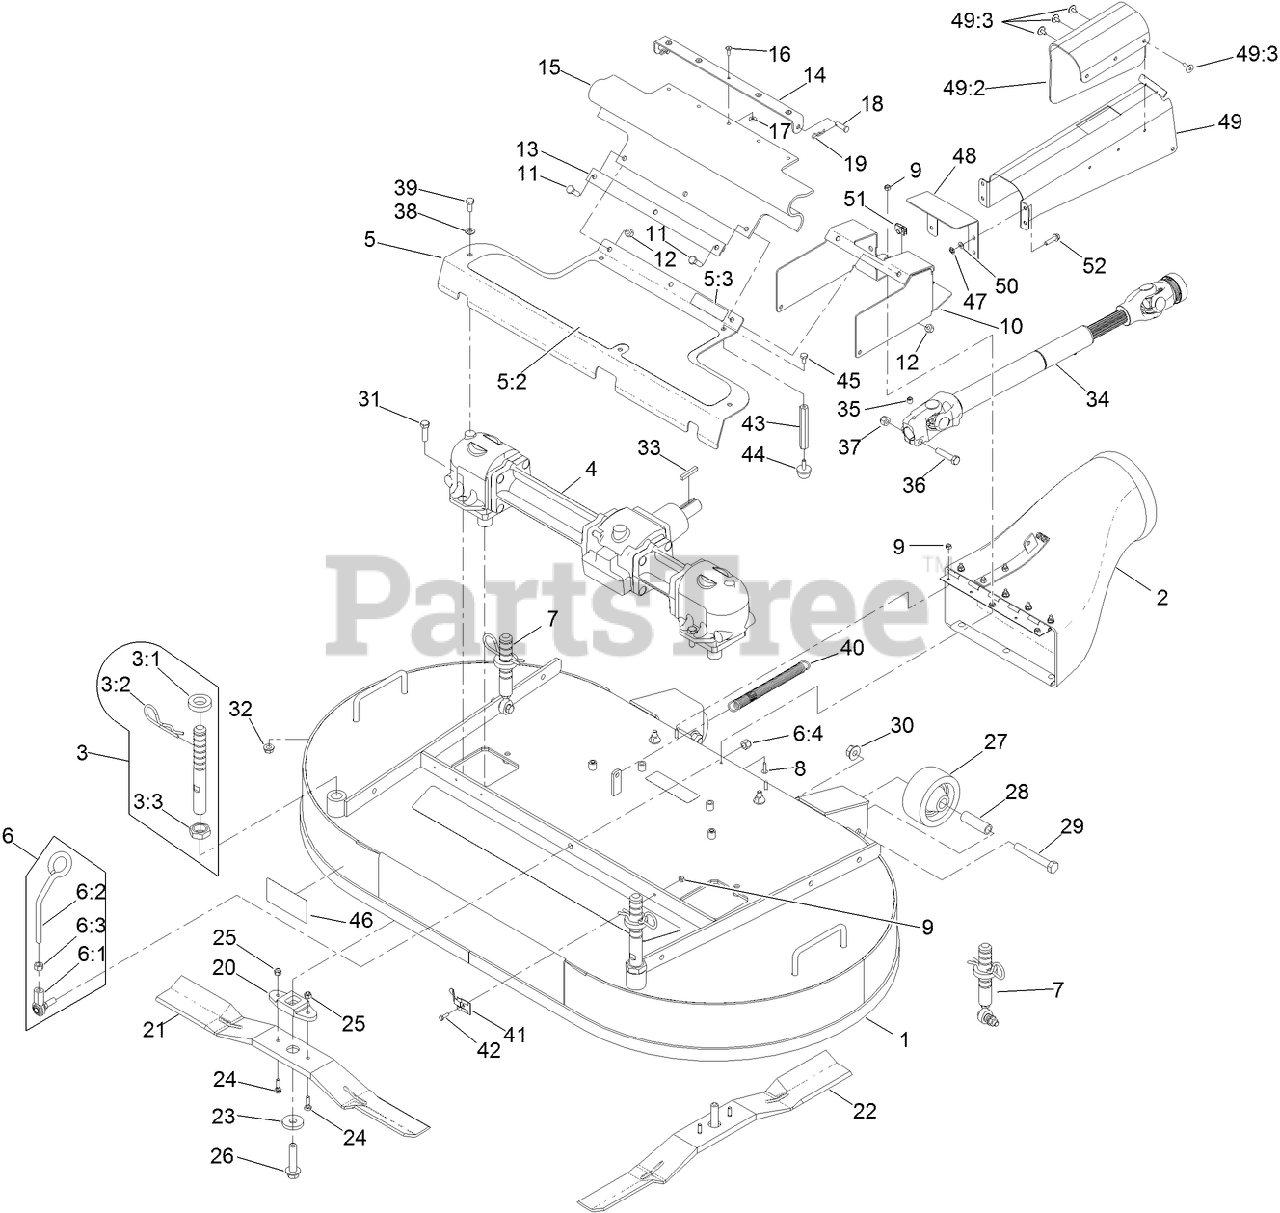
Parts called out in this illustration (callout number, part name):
1	DECK DECAL and BAFFLE ASM
2	DISCHARGE TUBE ASM
3	FRONT DECK HEIGHT ADJUST ASM
3:1	SPACER-DECK SUPPORT
3:2	PIN-CUT HEIGHT
3:3	NUT-JAM
4	GEAR BOX ASM
5	GEARBOX COVER ASM
5:2	PAD-ANTI SKID
5:3	DECAL-DANGER
6	DECK LATCH ASM
6:1	BALLJOINT-RH
6:2	LATCH-DECK
6:3	NUT-HEX
6:4	NUT-LOCK
7	REAR DECK HEIGHT ADJUST ASM
8	SCREW-HEAD, TRUSS
9	NUT-LOCK, NI
10	GUARD-PTO, FRONT
11	SCREW-HH
12	NUT-LOCK, NI
13	STRAP-DRIVE, LINE COVER
14	BRACKET-GUARD, PTO
15	GUARD-PTO
16	RIVET-BLIND
17	WASHER-FLAT
18	PIN-CLEVIS
19	PIN-COTTER
20	DRIVER-BLADE
21	BLADE-25IN, RH
22	BLADE-25IN, LH
23	WASHER
24	BOLT-SHEAR
25	NUT-LOCK, NI
26	BOLT-BLADE
27	ROLLER-DECK
28	SPACER-ROLLER
29	SCREW-HH
30	NUT-HHF
31	SCREW-HH
32	NUT-HHF, WHIZ
33	KEY-SQUARE
34	DRIVE SHAFT ASM
35	SCREW-SET, HSH
36	SCREW-HH
37	NUT-LOCK, NI
38	WASHER-PLAIN
39	SCREW-HH
40	SPRING-EXTENSION
41	CLIP-DECK, HOLD UP ROD
43	STAND-OFF
44	BUMPER
45	SCREW-HH
47	NUT-RETAINER
48	GUARD-PTO
49	PTO GUARD ASM
49:2	FLAP-RUBBER
49:3	RIVET-POP
50	WASHER-FLAT
52	SCREW-HHF
